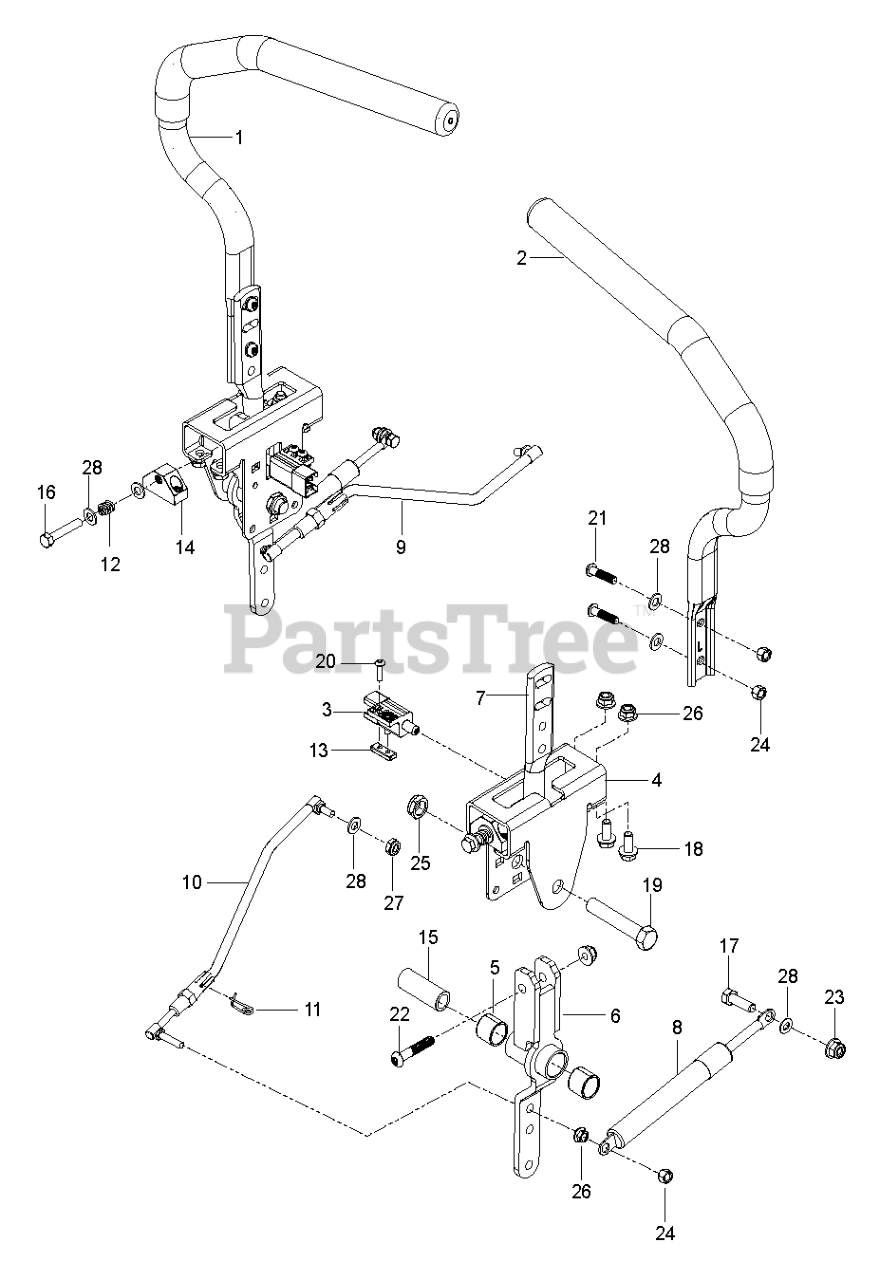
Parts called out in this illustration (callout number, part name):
1	TUBE.LEVER.CONTROL.ZTR.RT.428
2	TUBE.LEVER.CONTROL.ZTR.LT.428
3	Switch, Clutch, Attachment, Interlock (AYP part number)
4	BRACKET.CONTROLS.ZTR.X431
5	BEARING.PT.750
6	CONTROL.WELDMENT.RZ
7	LEVER.HANDLE MOUNT
8	DAMPENER
9	ROD.ASM.RH.ADJUSTABLE
10	ROD.ASM.LH.ADJUSTABLE
11	RETAINER.CLIP.SPRING.S
13	PLATE NUT ZTR
14	BLOCK TRACKING CONTROL ZTR
15	SPACER.PIVOT.CONTROL
16	CAPSCREW 5/16 X 1/1/2 HEX HEAD
17	HCS 5/16C X 1
18	HHFS 5/16-18 X 3/4
19	HCS 1/2-13 X 2-3/4 GD 5 ZD
20	SCR #10-24 X .75 SKT HD BLK
21	SCREW.BUTTHEAD.5/16-18X1-1.25
22	SCREW.CAP.SOCKET.6PT.5/16-18
23	NUT 5/16C WHIZ
24	Locknut, Hex, with Washer Insert 5/16-18 (AYP part number)
25	NUT 1/2-13 HEX JM NYL
26	5/16-18 NYLOC FLANGE NUT
27	5/16-18 THIN PROF NY
28	Washer, Nut Lock Hex w/Ins. 5/6-18 (AYP part number)
